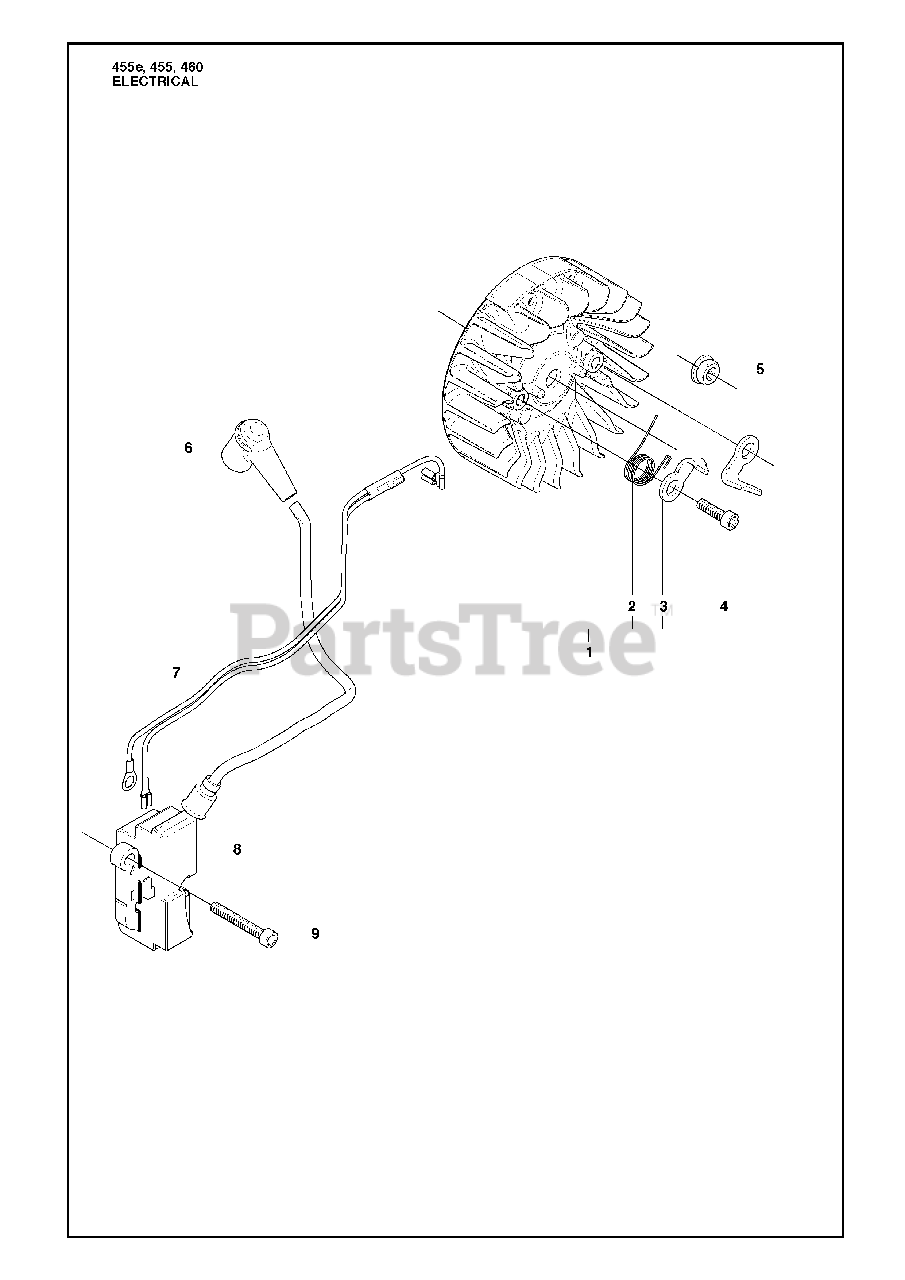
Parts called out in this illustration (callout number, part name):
5	NUT W/ WASHER
6	SPARK PLUG CONN. KIT
7	CABLE ASSY
8	IGNITION MODULE
